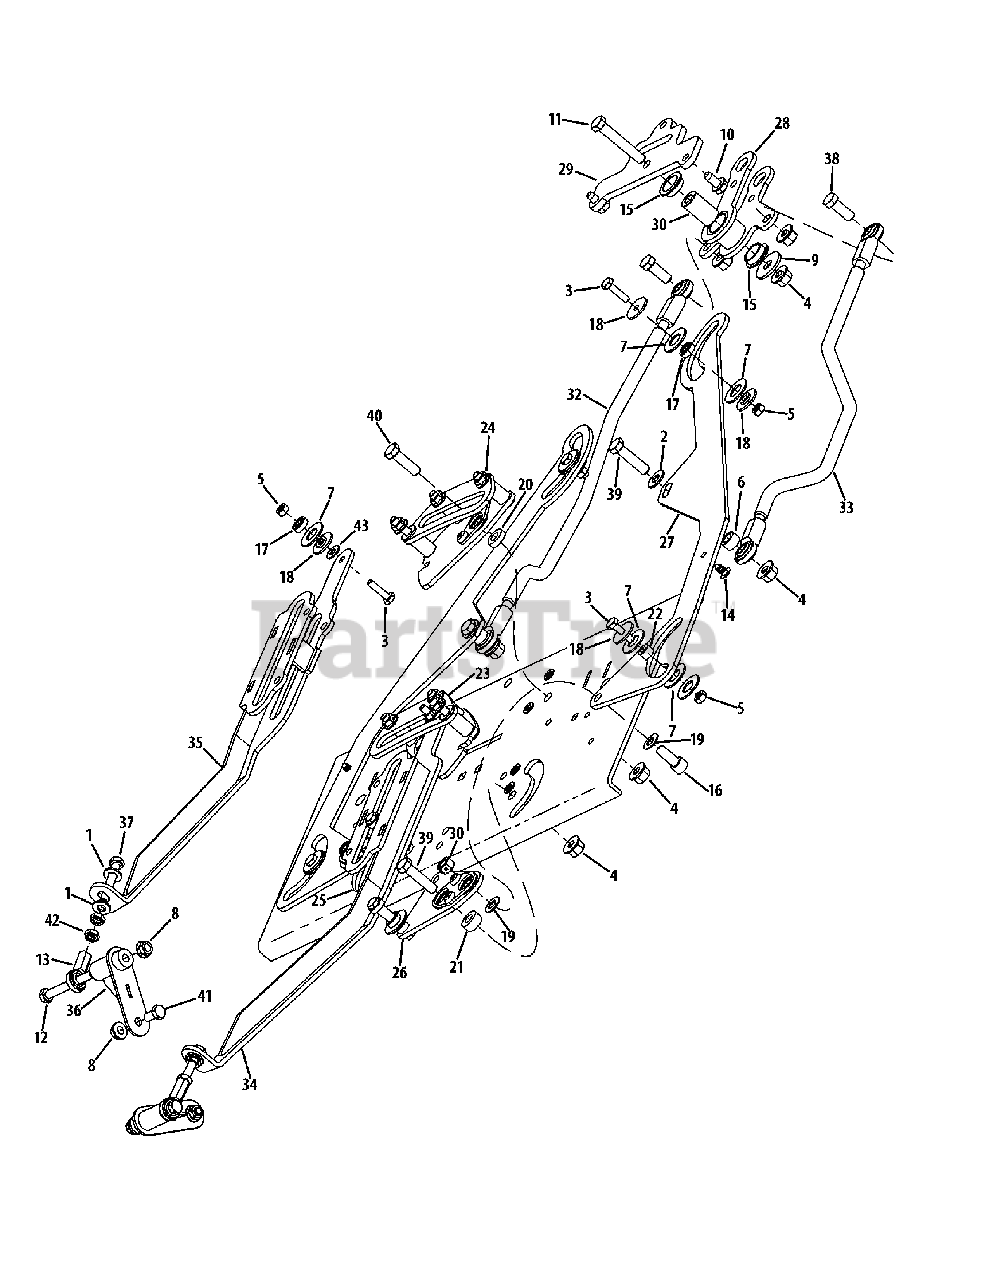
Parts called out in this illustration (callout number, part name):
1	Washer, .344 x .688 x .063
2	Washer, .406 x .813 x .063
3	Hex Screw, 1/4-20 x 1.00
4	Flange Counter Lock Nut, 3/8-16
5	Counter Lock Nut, 1/4-20
6	Spacer, .407 x .625 x .375
7	Washer, .550 x 1.25 x .068
8	Flange Counter Lock Nut, 5/16-18
9	Washer, .411 x 1.25 x 1.00
10	Flange Screw, 5/16-18 x .75
11	Hex Screw, 3/8-16 x 2.25
12	Hex Screw, 5/16-18 x 2.75
13	Rod End, 5/16
14	Rivet, 1/4 x .625
15	Flange Bearing, .752 x 1.25 x .305
16	Socket Head Screw, 3/8-16 x .88
17	Ball Bearing, .25 x .625 x .196
18	Shoulder Spacer, .251 x 1.00 x .06
19	Spacer, .381 x .750 x .040
20	Spacer, .381 x .75 x .150
21	Spacer, .381 x .750 x .312
22	Spacer, .256 x .500 x .330
23	LH Speed Control Cam Assembly
24	RH Speed Control Cam Assembly
25	LH Steering Pivot Assembly
26	RH Steering Pivot Assembly
27	Control Link Plate
28	Front Steering Pivot Assembly
29	Steering Pivot Mount Plate
30	Spacer, .385 x .750 x 1.28
31	Flat Washer, .25 x .630 x .0515
32	LH Control Rod Assembly
33	RH Control Rod Assembly
34	Pump Control Arm Assembly
35	RH Pump Control Arm Assembly
36	Pump Control Spacer Assembly
37	Hex Screw, 5/16-24 x 2.00
38	Hex Screw, 3/8-16 x 1.00
39	Hex Screw, 3/8-16 x 1.50
40	Hex Screw, 3/8-16 x 1.25
41	Hex Screw, 5/16-18 x .625
42	Jam Nut, 5/16-24
